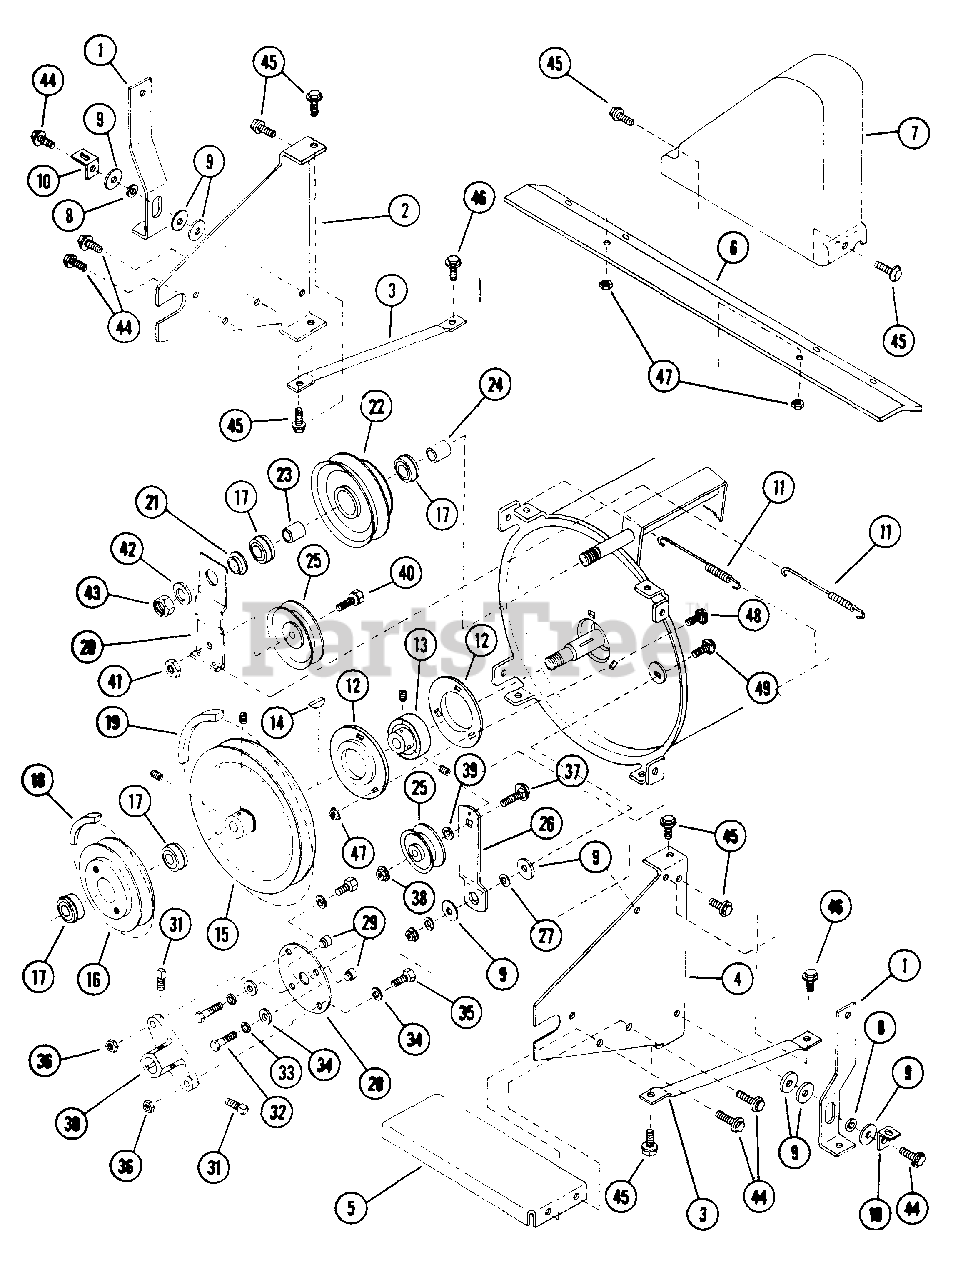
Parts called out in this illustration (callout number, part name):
1	LINK, Lift
2	BRACKET, LH Mounting
3	BRACE, Side
4	BRACKET, RH Mounting
5	BRACE, Center
6	BAR, Stiffener
7	COVER, Belt Guard
8	SPACERS
9	WASHER, 5/16" x 1-1/4" x 3/32" Flat
10	BRACKET, Shift
11	SPRING, Idler
12	HOUSING, Bearing
13	BEARING
14	KEY, 3/16 x 7/8" Woodruff
15	PULLEY, 8.36" O.D.
16	PULLEY, 5.25 OD (Iron)
17	BEARING
18	BELT, 41"
19	BELT, Blower
20	ARM, Idler
21	BUSHING
22	SHEAVE, Reduction
23	SPACER, .765"
24	SPACER, .625"
25	IDLER
26	ARM, Idler
27	SPACER
28	DISC, Flex-Coupling
29	SPACER, Flex Coupling
30	HUB, Flex Coupling
31	SETSCREW, 5/16-18x1/2 Square Head
32	CAPSCREW, 3/8-16x1-1/4 Hex Head
33	LOCKWASHER, 3/8 Split
34	WASHER, 3/8" Flat
35	CAPSCREW, 3/8cx1 Hex Head
36	LOCKNUT, 3/8C Hex
37	CARRIAGE BOLT, 3/8Cx1-1/2 SN
38	LOCKNUT, 3/8C Hex
40	CAPSCREW, 3/8-16x1-1/2 Hex Head
41	NUT, 3/8-16 Hex
42	WASHER, 5/8-18
43	LOCKNUT, 5/8-18 Hex Jam
44	SCREW, 5/16-18x1 Self Tap
45	SCREW, 5/16-18x5/8 Self Tap
46	BOLT, 5/16-18x5/8 Hex Flange Lock
47	LOCKNUT, 5/16-18 Hex Flange
48	CARRIAGE BOLT, 5/16-18x3/4 Short Neck
49	CARRIAGE BOLT, 5/16-18x1 Short Neck
